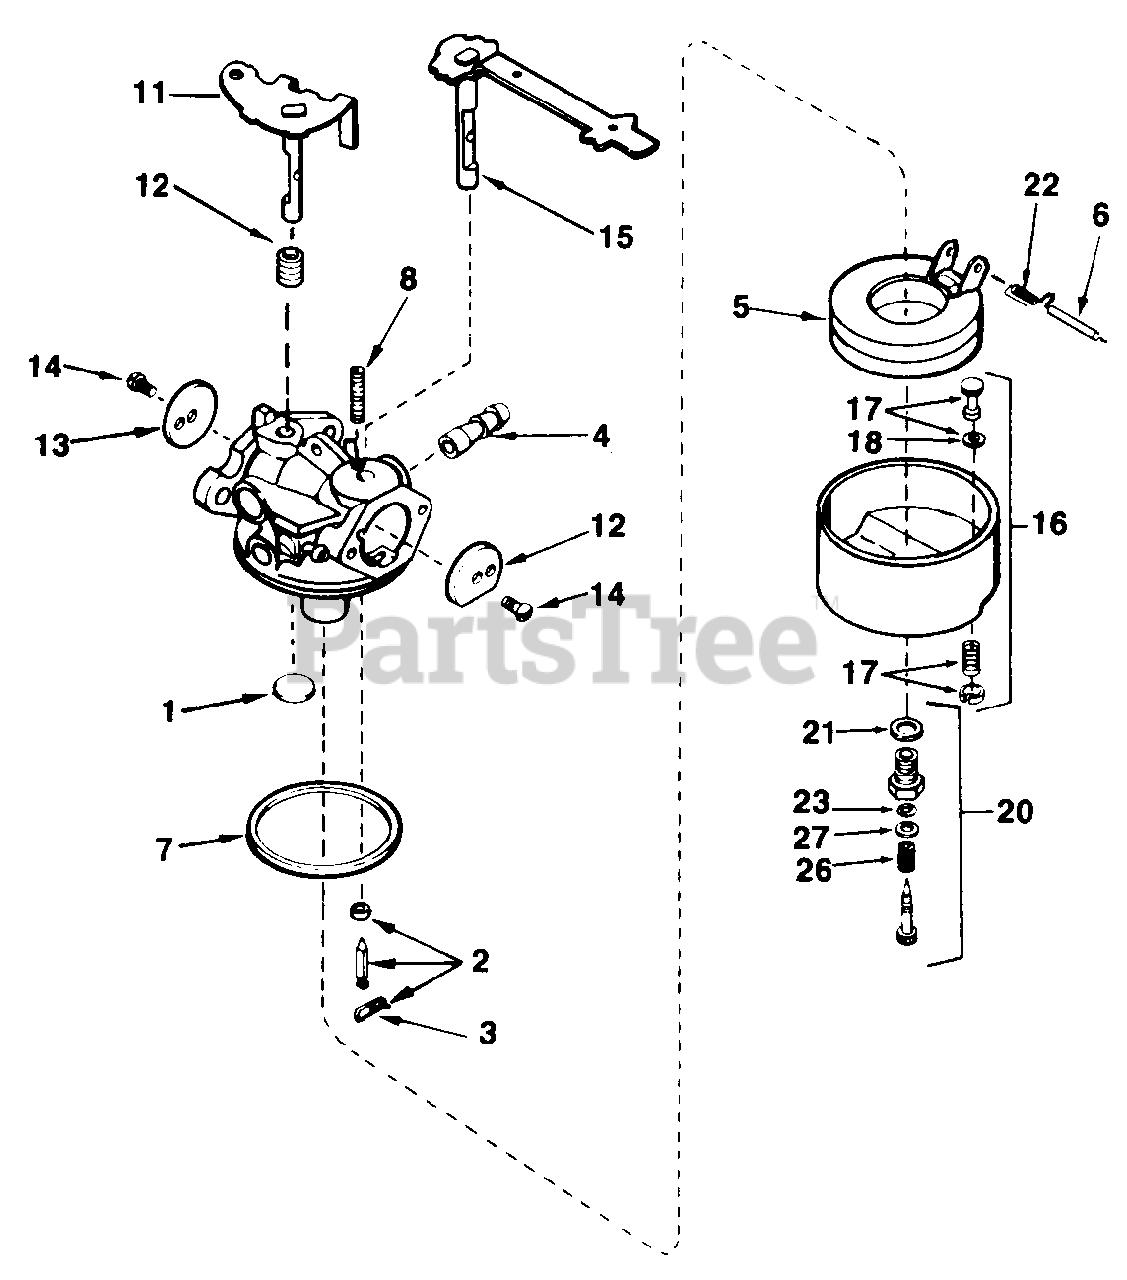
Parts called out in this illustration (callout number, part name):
1	Plug, Welch
2	Inlet Needle, Seat & Clip Ass'y.
3	Clip, Inlet Needle
4	Fitting, Fuel Inlet
5	Float, Carburetor
6	Shaft, Float
7	"O" Ring, Bowl-to-Body
8	Spring, Choke Positioning
11	Shaft & Lever Ass'y., Throttle
12	Shutter, Choke
13	Shutter, Throttle
14	Screw, Throttle & Choke Shutter
15	Shaft & Lever Ass'y., Choke
16	Bowl Ass'y., Float
17	Drain Plunger Ass'y.
20	Main Adjustment Screw Ass'y.
21	Gasket, Bowl-to-Body
22	Spring, Float Shaft
26	Spring, Adjustment Screw
